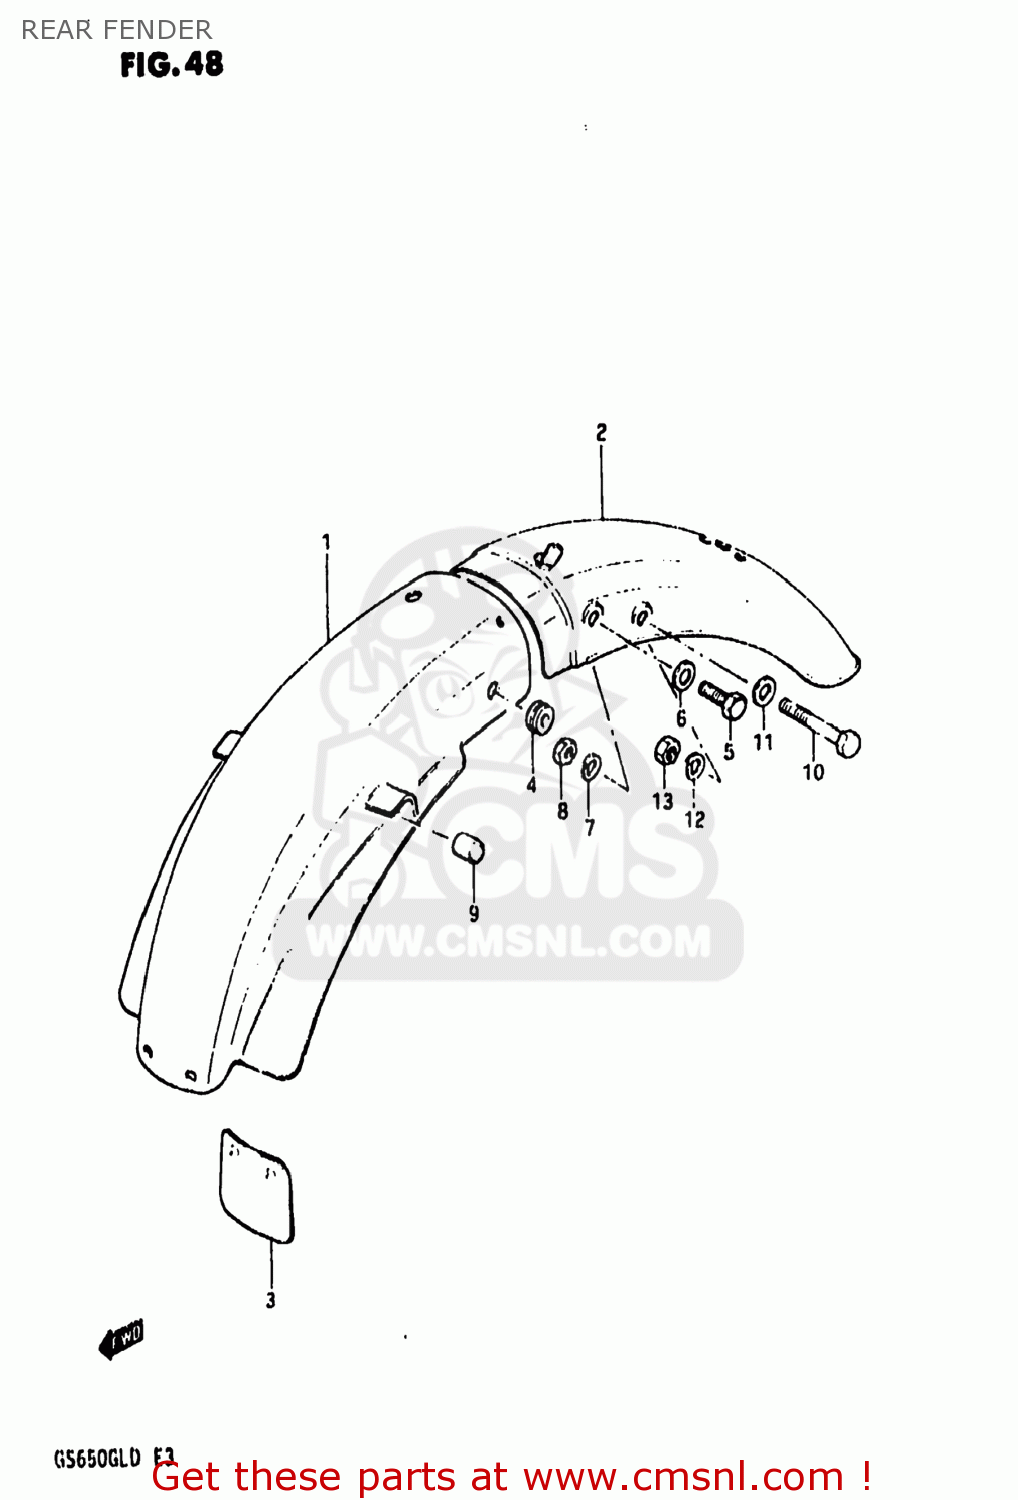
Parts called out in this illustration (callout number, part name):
1	BODY,REAR FENDER,FRONT
2	FENDER,REAR
3	GUIDE,RR FENDER MUD
4	CUSHION
5	BOLT
6	WASHER
7	LOCK WASHER
8	NUT 8MM
9	CUSHION
10	BOLT
11	WASHER
12	LOCK WASHER
13	NUT 8MM
